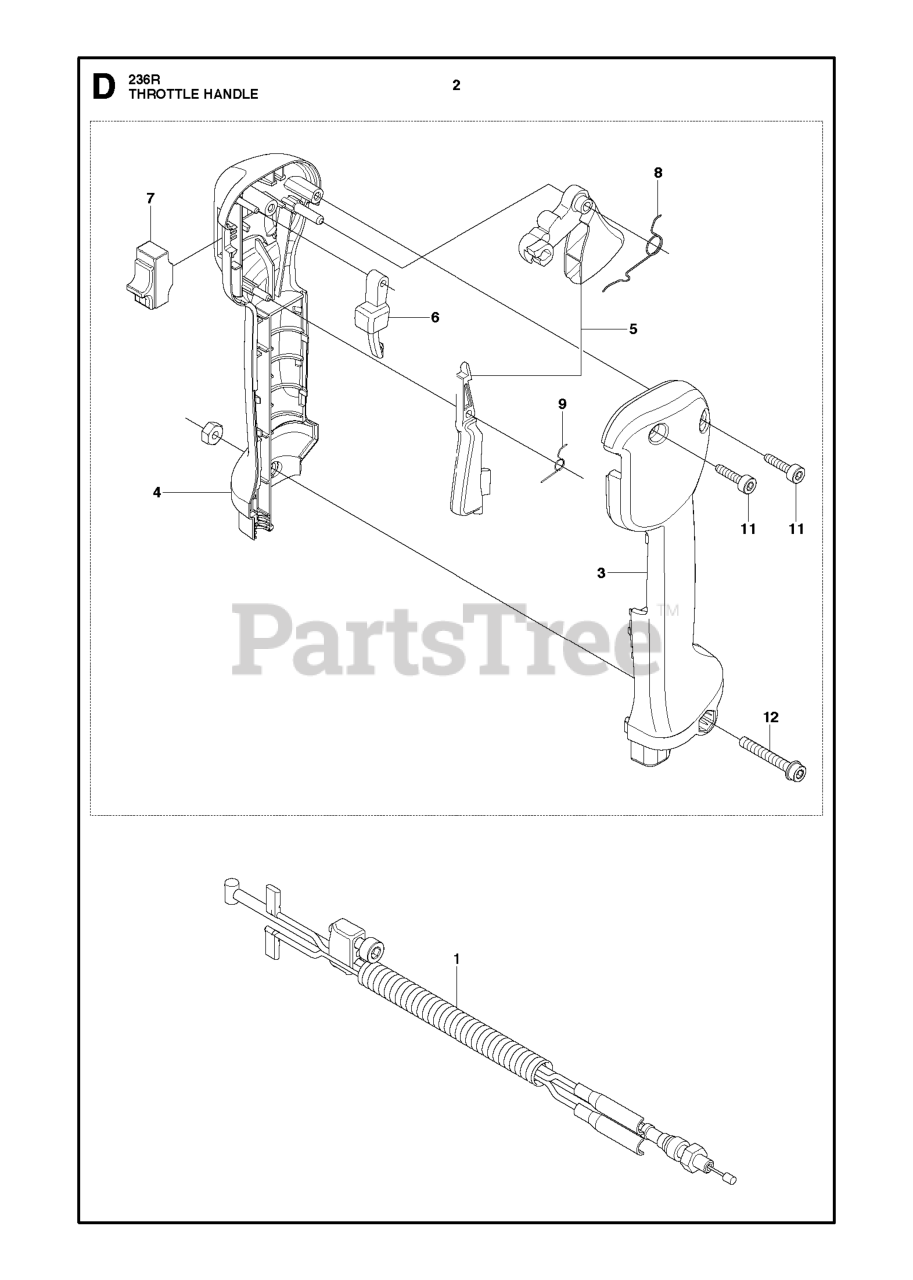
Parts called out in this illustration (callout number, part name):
5	THROTTLE CONTROL
6	STARTER THROTTLE LOCK
7	START/STOP SWITCH
11	SCREW IHSCT MT4X18 10.9 ZN/FE
12	SCREW IHSCFM
